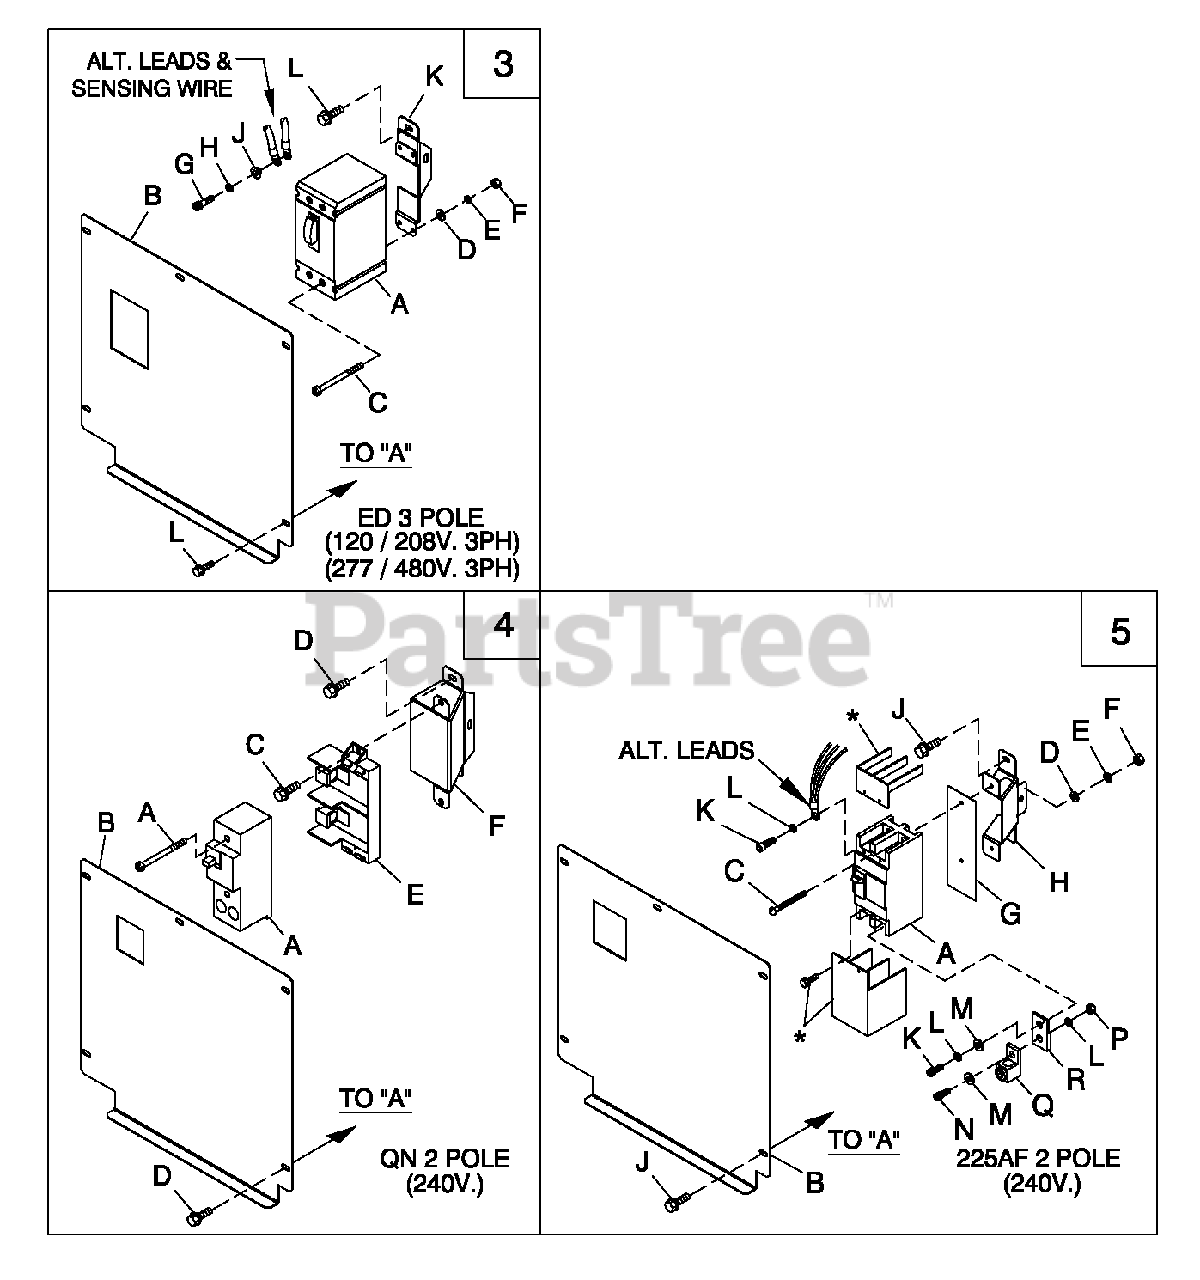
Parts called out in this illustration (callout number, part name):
3	CB 0030A 3P 480V S ED4 LL
4	UL BREAKER QN
5	UL BREAKER
A	CB 0035A 3P 480V S ED4 LL
B	CB COVER 20-30K 3P (ED)
C	SCREW RHM #8-32 X 4-1/2
D	WASHER FLAT #8 ZINC
E	WASHER LOCK #8-M4
F	NUT HEX #8-32 STEEL
G	SCREW SHC 1/4-28 X 3/4 G8.8 NZ
H	WASHER LOCK M6-1/4
J	WASHER-STEP 1/2ODX9/32ID BRASS
K	CIRCUIT BREAKER SUPPORT (ED)
L	SCREW HWHTF M6-1.0 X 16
A	CB 0150A 2P 240V S QN2 LL
B	CONBOX FRONT COVER 1.6L QN 2P
C	SCREW HHTT M5-0.8 X 10 BP
D	SCREW HWHTF M6-1.0 X 16
E	BASE, QN CIRCUIT BREAKER
F	BREAKER SUPPORT BRACKET 30KW
A	CB 150A 2 POLE 240V 225AF
B	CB COVER 30K G 225AF
C	SCREW RHM #8-32 X 3-1/4
G	INSULATOR CB 2P 225AF
H	CIRCUIT BREAKER SPPRT G 225AF
J	SCREW HWHTF M6-1.0 X 16
K	SCREW SHC M8-1.25 X 20 G8
L	WASHER LOCK M8-5/16
M	WASHER FLAT 5/16-M8 ZINC
N	SCREW SHC M8-1.25 X 25 G12.9
P	NUT HEX M8-1.25 G8 CLEAR ZINC
Q	LUG SLDLSS 300 MCM-6 AL/CU
R	BUS BAR 200A LUG ADAPTOR
